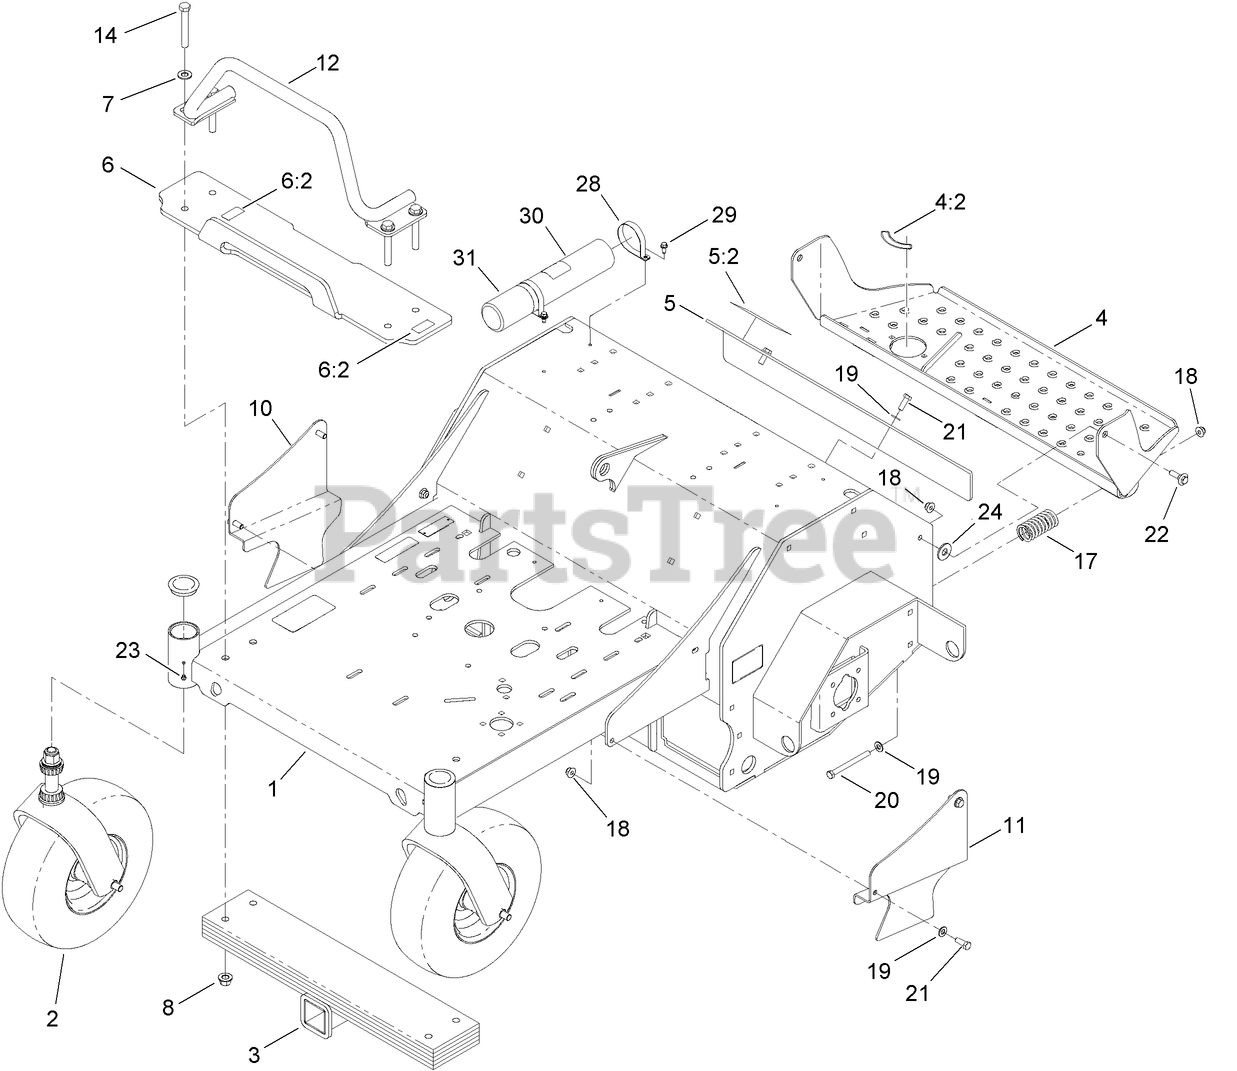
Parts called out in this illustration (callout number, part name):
1	MAIN FRAME AND DECAL ASM
2	FRONT CASTER AND FORK ASM
4	PLATFORM ASM
4:2	DECAL-TINE GROUND ENGAGEMENT
5	ACCESS COVER ASM
5:2	DECAL-OPERATION, TINE GROUND (CE)
6	WEIGHT MOUNT PLATE ASM
6:2	DECAL-SURFACE, HOT
7	WASHER-FLAT
8	NUT-LOCK
10	GUARD-CHAIN, RH
11	GUARD-CHAIN, LH
12	GUARD-MUFFLER
14	SCREW-HH
17	SPRING-COMPRESSION
18	NUT-HF, NI
19	WASHER-FLAT
20	SCREW-HH
21	SCREW-HH
22	SCREW-SHOULDER, HWH
24	WASHER-FLAT
28	R-Clamp
29	SCREW-HWH
30	TUBE-MANUAL
31	CAP-HOUSING
